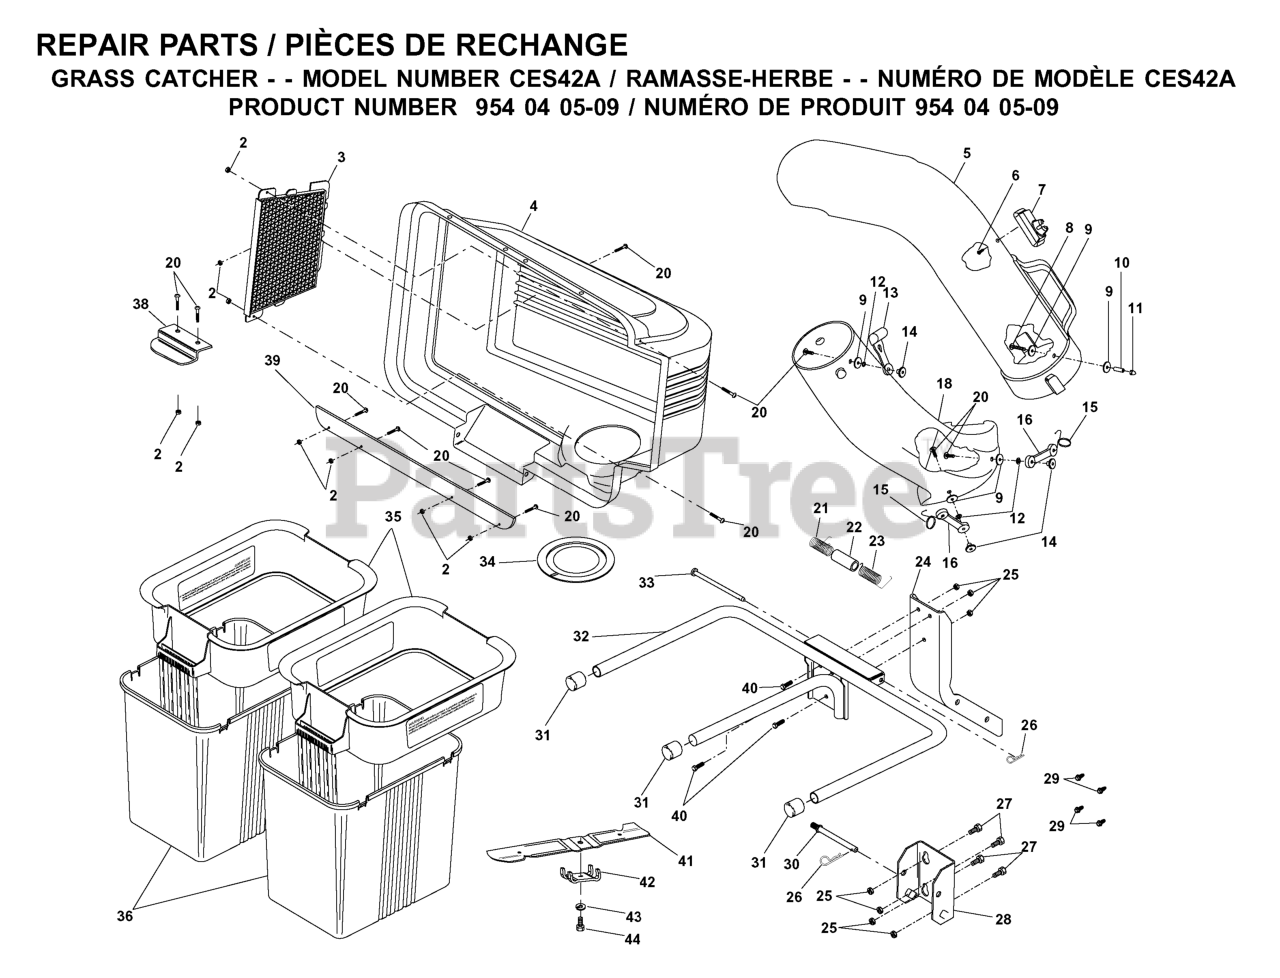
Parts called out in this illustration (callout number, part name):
2	Nut, Crownlock #10-24
3	COVER SCREEN
4	COVER
5	CHUTE.UPPER.42"
7	INDICATOR DUMP BAG
8	SCREW
11	NUT
12	LOCKWASHER #10
13	LATCH.HOOD.
14	WELDNUT
15	HOOK LATCH
16	RUBBER LATCH
18	LOWER CHUTE FOR 42" BAGGER
20	SCREW
21	SPRING COVER LH
22	SPACER.COVER.BAGGER
23	SPRING COVER RH
24	POST.SUPPORT.BAGGER.2BIN
25	LOCKNUT
26	RETAINER-SPRNG RB
27	BOLT
28	MOUNTING BRACKET, BAGGER
29	SHOULDER BOLT 5/16-18TT
30	SUPPORT POST PIN
31	PLUG, TUBING END
32	BAGGER FRAME
33	HINGE PIN
34	GASKET.COVER.BAGGER
35	CONTAINER TOP
36	CONTAINER BOTTOM
38	LATCH CER38
39	STRIP.REINFORCE.BAGGER.2BIN.BL
40	BOLT.CARR.SQNK.5/16-18UNC.X3/4
41	42" CROSS BLADE
42	ADAPTER.BLADE.PNT.CSS.36/38/42
43	LOCKWASHER
44	BOLT.3/8-24X1.25 GR8
